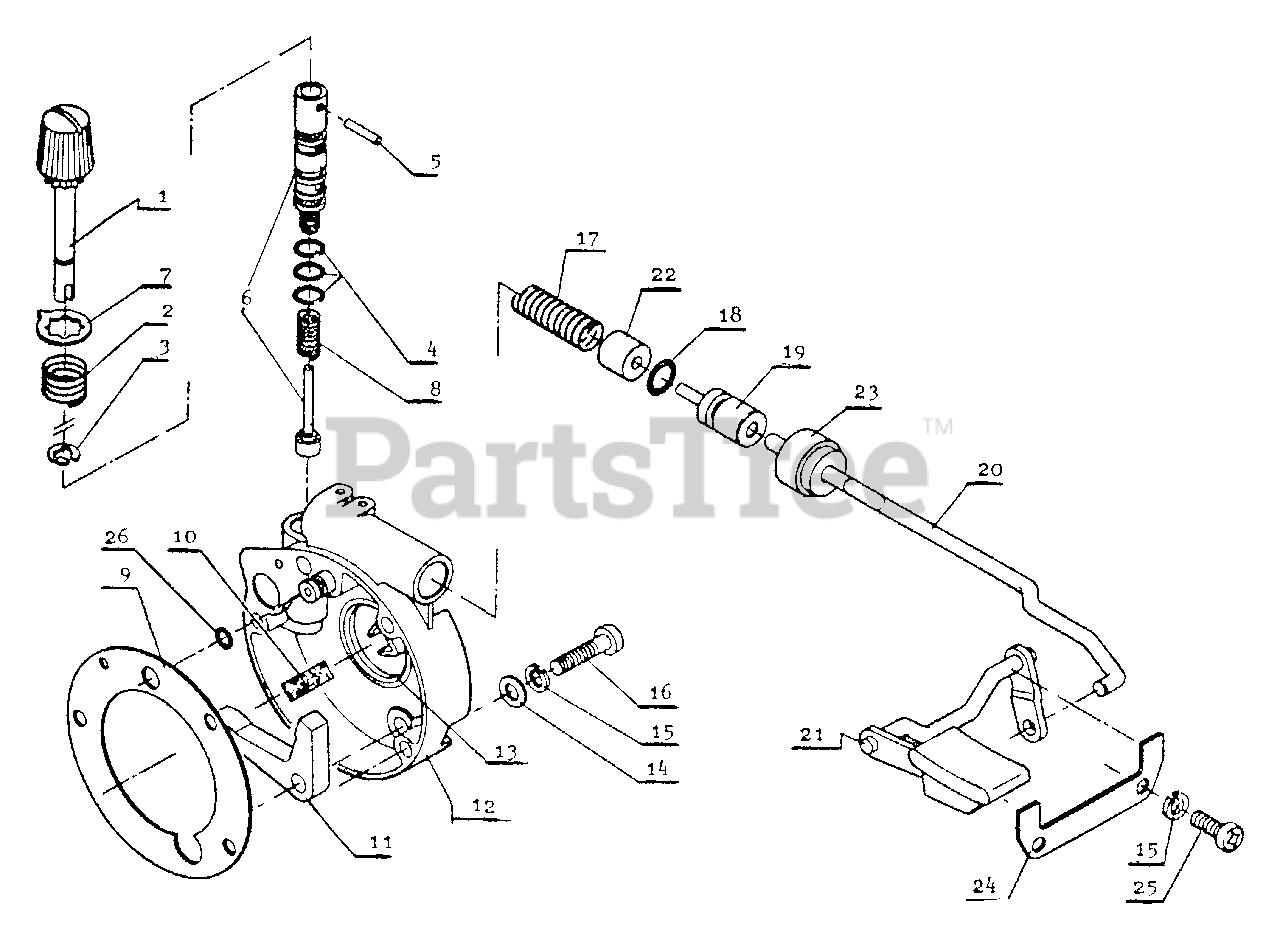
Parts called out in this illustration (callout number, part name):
1	KNOB
2	SPRING
3	E-RING 4
5	PIN, SPRING
6	PUMP KIT
7	DIAL, AUTO-OILER
9	OIL PUMP BODY GASKET
10	PAD
11	CAM ARM
12	OIL PUMP BODY
13	SEAL, OIL
14	WASHER 4 MM
15	WASHER, SPRING 4 MM
16	SCREW 4×18
17	SPRING, OIL PUMP
18	O-RING 6 MM
19	PISTON, OIL PUMP
20	OIL PUMP ROD
21	OIL PUMP LEVER
22	RETAINER, SPRING
23	PISTON COVER
24	OIL PUMP LEVER RETAINER
25	SCREW 4×10
